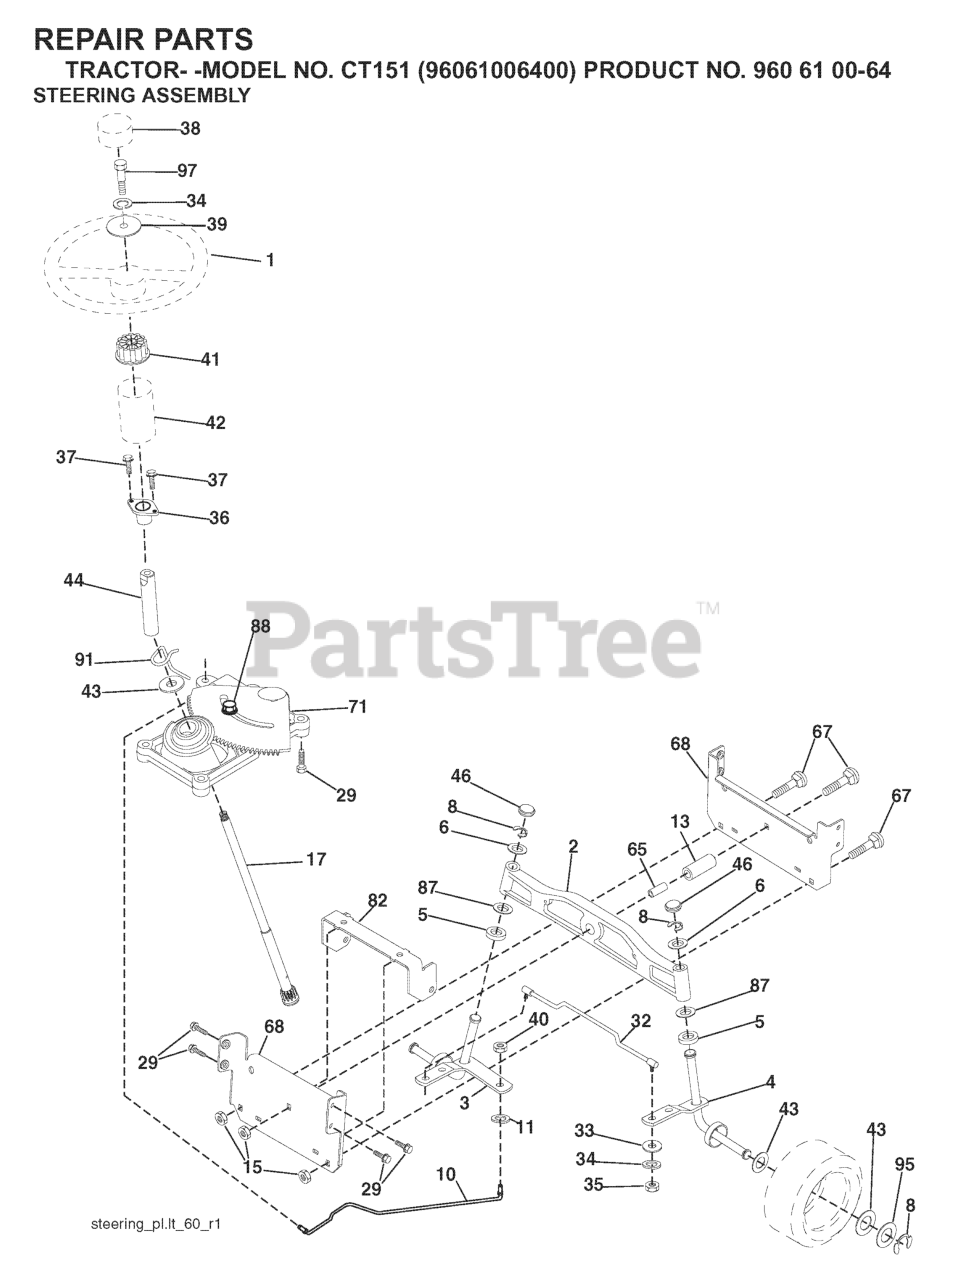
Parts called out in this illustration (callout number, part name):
1	STEERING WHEEL
2	AXLE ASSY FRONT
3	SPINDLE.ASM.LH.15"TIRES
4	SPINDLE.ASM.RH.15"TIRES
5	THRUST WASHER
10	DRAGLINK.15".TIRES.2001
11	WASHER, LOCK 3/8
13	TUBE, PIVOT AXLE
15	NUT
17	SHAFT STEERING SPLINE
29	SCREW, 3/8-16X3/4
32	ROD.ASM.TIE.BALL.JOINT.NOVAN
33	WASHER M
34	WASHER.LOCK.HVY.HLCL.SPR.5/16
35	NUT, CROWNLOCK
36	BUSHING, STEERING
37	SCREW.TT.#10-32X.5.3/8.FLANGE
38	INSERT.CAP.STRG.WH.GRAY
39	WASHER.11/32
40	NUT CROWNLOCK 3/8-24
41	ADAPTER, WHEEL STNG..
42	BOOT STEERING
44	SHAFT.EXTEN.STRG.SPLINE
46	CAP.SPINDLE.BLACK
65	SPACER BRACE AXLE
67	BOLT CARRIAGE
68	BRACE.AXLE.15"TIRES
71	STEERING ASM
82	BRACKET.SUSP.CHASSIS.FRONT.15
87	WASHER, FLAT .781 X 1 1/2"
88	BOLT, SHOULDER 7/16-20
91	CLIP.STEERING
95	WASHER.HARDENED
